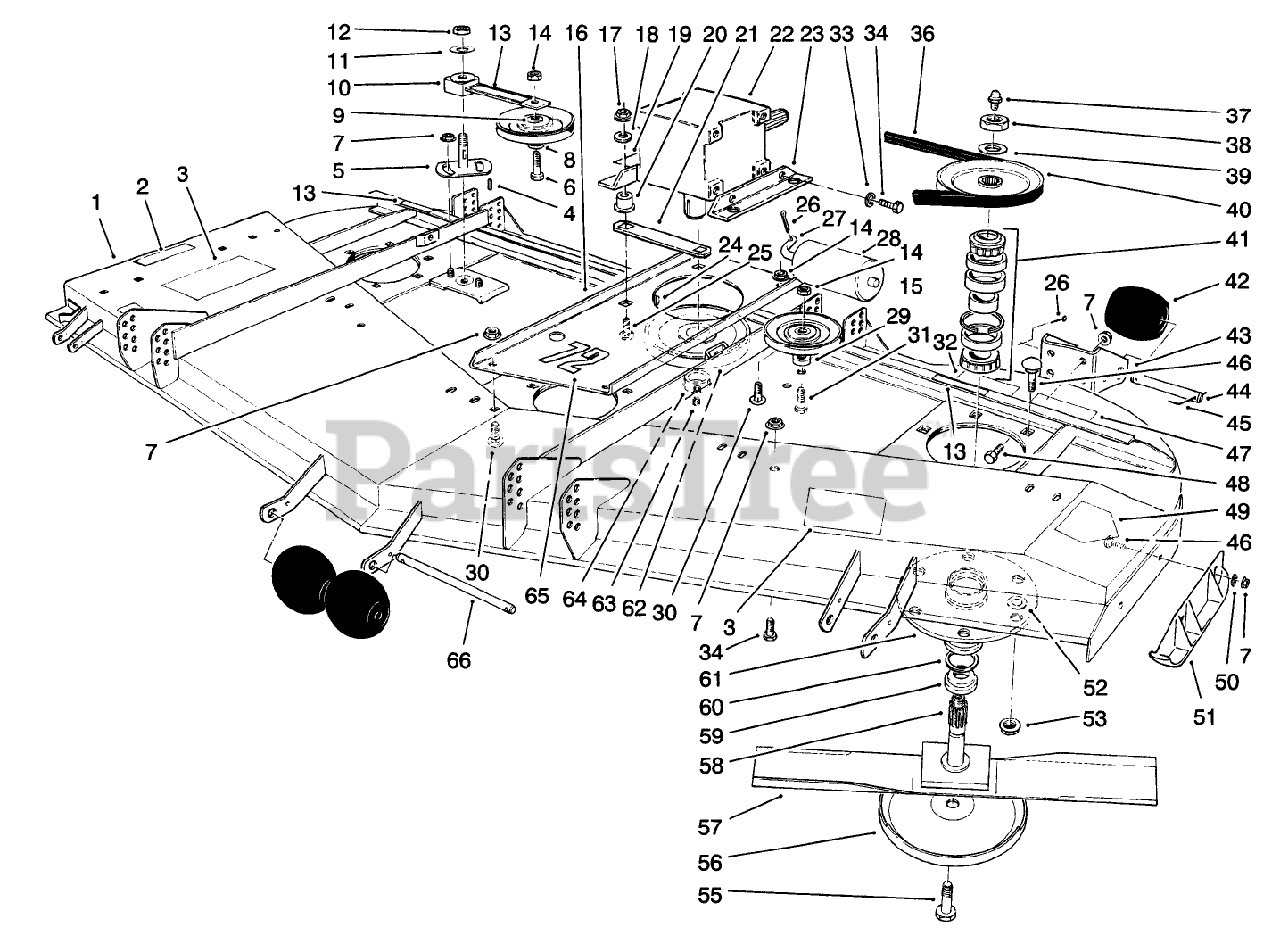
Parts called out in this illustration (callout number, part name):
1	Housing (Incl. Ref. #2-4, 7, 13, 32, & 49)
2	DECAL-DANGER
3	DECAL-DANGER, THROWN OBJECT
4	KEY-SQUARE
5	PLATE-IDLER
6	SCREW-HH
7	NUT-HHF, WHIZ
8	BUSHING-PULLEY
9	WASHER-FLAT
10	IDLER ARM ASM
11	WASHER-FLAT
12	NUT-LOCK, NI
13	DECAL-DANGER
14	NUT-HEX
15	PULLEY-IDLER
16	Base-Gear Box
17	NUT-LOCK, SIDE
18	WASHER
19	DECAL-OIL
20	MOUNT
21	Cover-Gear Box
22	Gearbox
23	Bracket-Gearbox
24	KEY-WOODRUFF
25	SCREW-CARR
26	PIN-COTTER
27	SHAFT-ROLLER, REAR
28	ROLLER-DECK
29	SPACER
30	SCREW-CARR
31	SCREW-HH
32	DECAL-TORQUE
33	WASHER-LOCK
34	SCREW-HH
36	V-BELT (72)
37	FITTING-GREASE
38	NUT-HEX
39	WASHER
40	PULLEY & HUB ASM, WELDED
41	BEARING ASM
42	ROLLER
43	Bracket-Roller
44	SHAFT-ROLLER
45	PIN-SPECIAL
46	SCREW-CARR
47	DECAL-WARNING
48	SCREW-HH
49	DECAL-DANGER
50	LOCKWASHER-PYRAMID
51	Skid
52	WASHER-FLAT
53	NUT-HF
55	BOLT-BLADE
56	CUP-SCALP, ANTI
57	Blade
58	SHAFT
59	SPACER
60	SEAL-OIL
61	HOUSING-SPINDLE
62	PULLEY
63	SCREW-SET, HSH
64	Bushing-Taper Lock (Incl. Ref. #63)
65	DECAL
66	SHAFT-ROLLER
